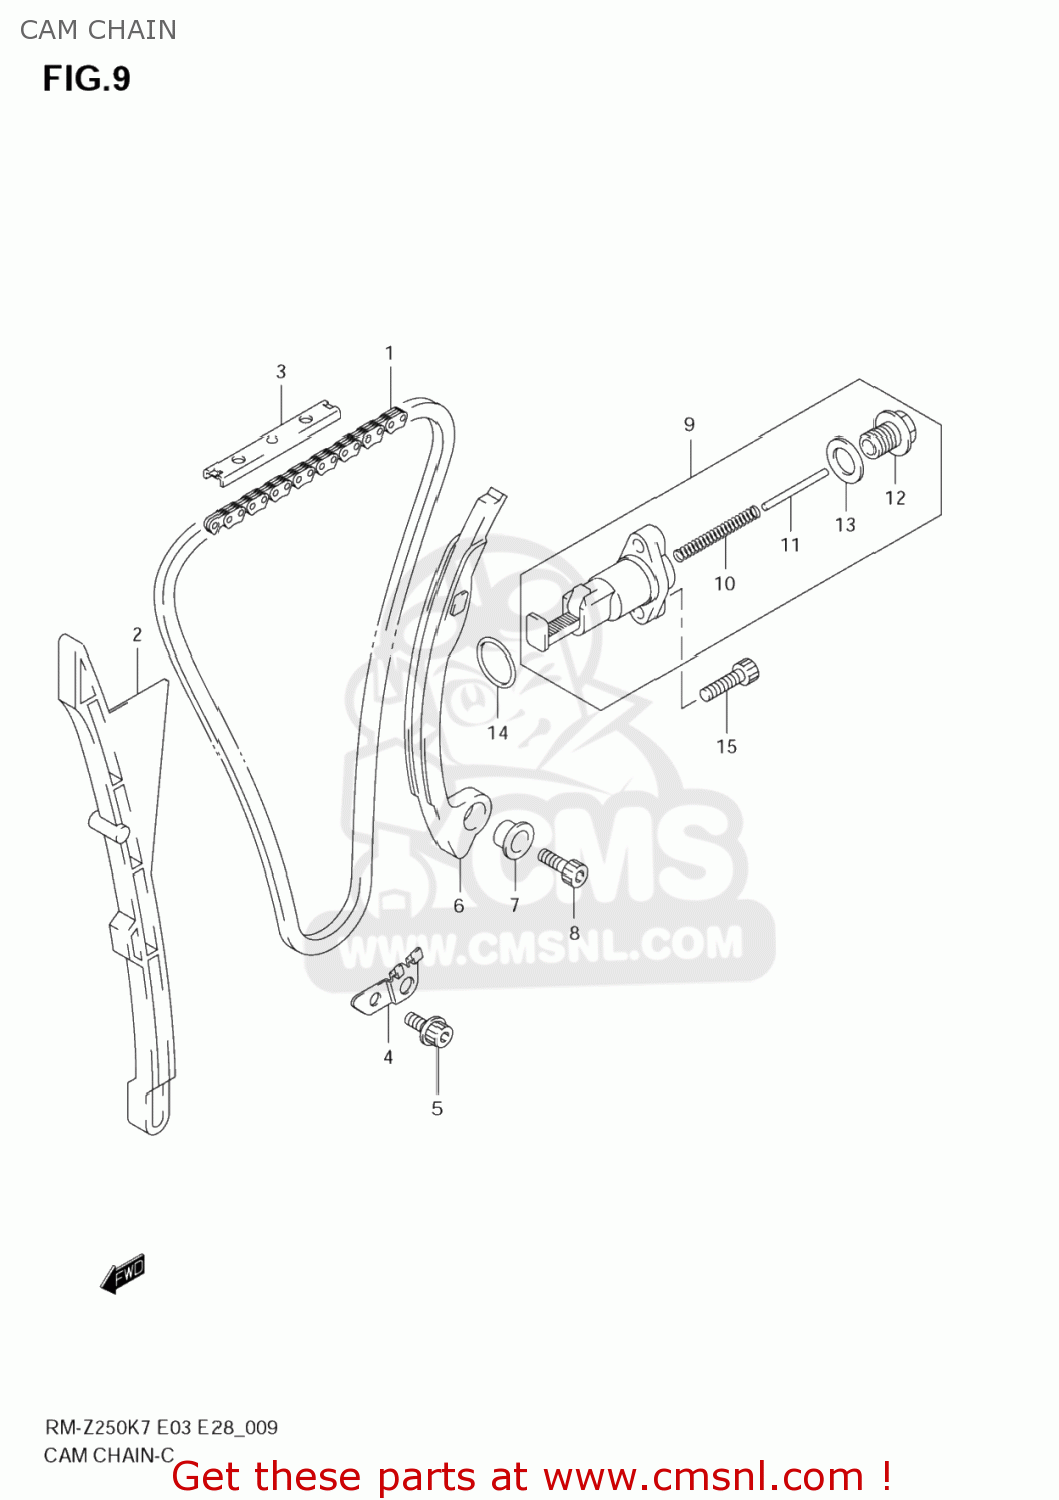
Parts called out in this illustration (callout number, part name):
1	CHAIN,CAMSHAFT DRIVE
2	GUIDE,CAM CHAIN NO.1
3	GUIDE,CAM CHAIN NO.2
4	RETAINER,CAM CHAIN GUIDE NO.1
5	BOLT
6	TENSIONER,CAM CHAIN
7	SPACER,CAM CHAIN TENSIONER
8	BOLT
9	ADJUSTER ASSY,TENSIONER
10	SPRING,ADJUSTER
11	BAR,ADJUSTER
12	PLUG,ADJUSTER
13	GASKET,TENSIONER ADJUSTER (NAS)
14	O RING(D:1.9,ID:18.8)
15	BOLT
